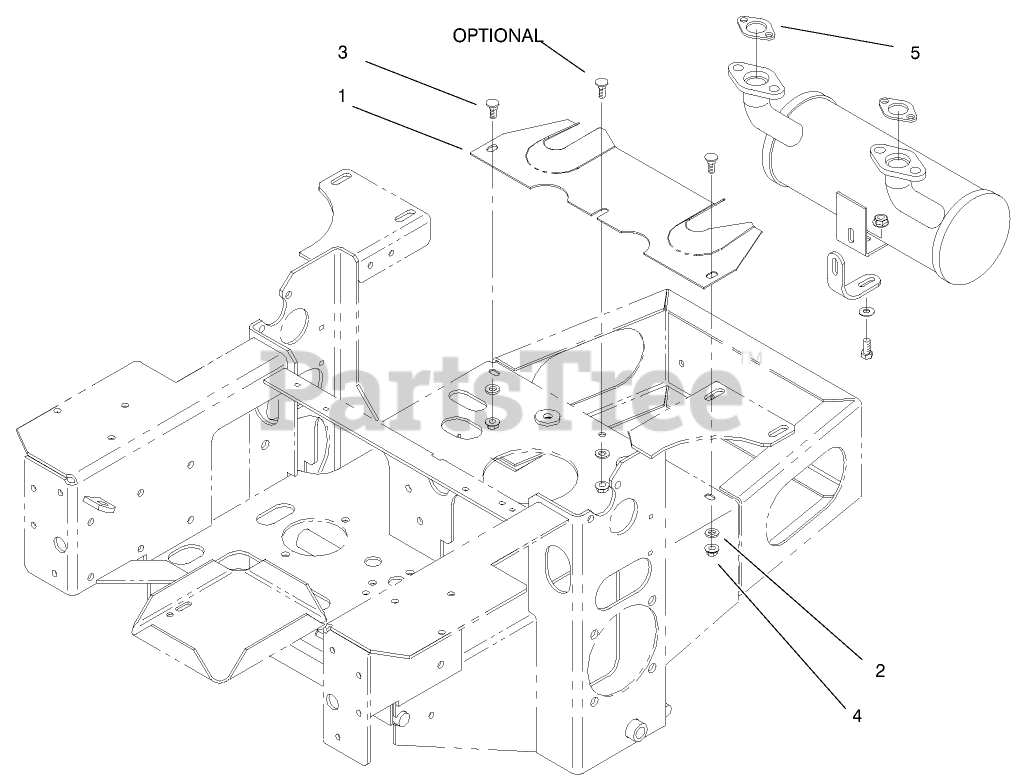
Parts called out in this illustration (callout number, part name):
1	Heat Shield
2	WASHER-PLAIN
3	BOLT-CARR
4	NUT-LOCK, NI
5	Gasket-Exhaust 17 Hp
